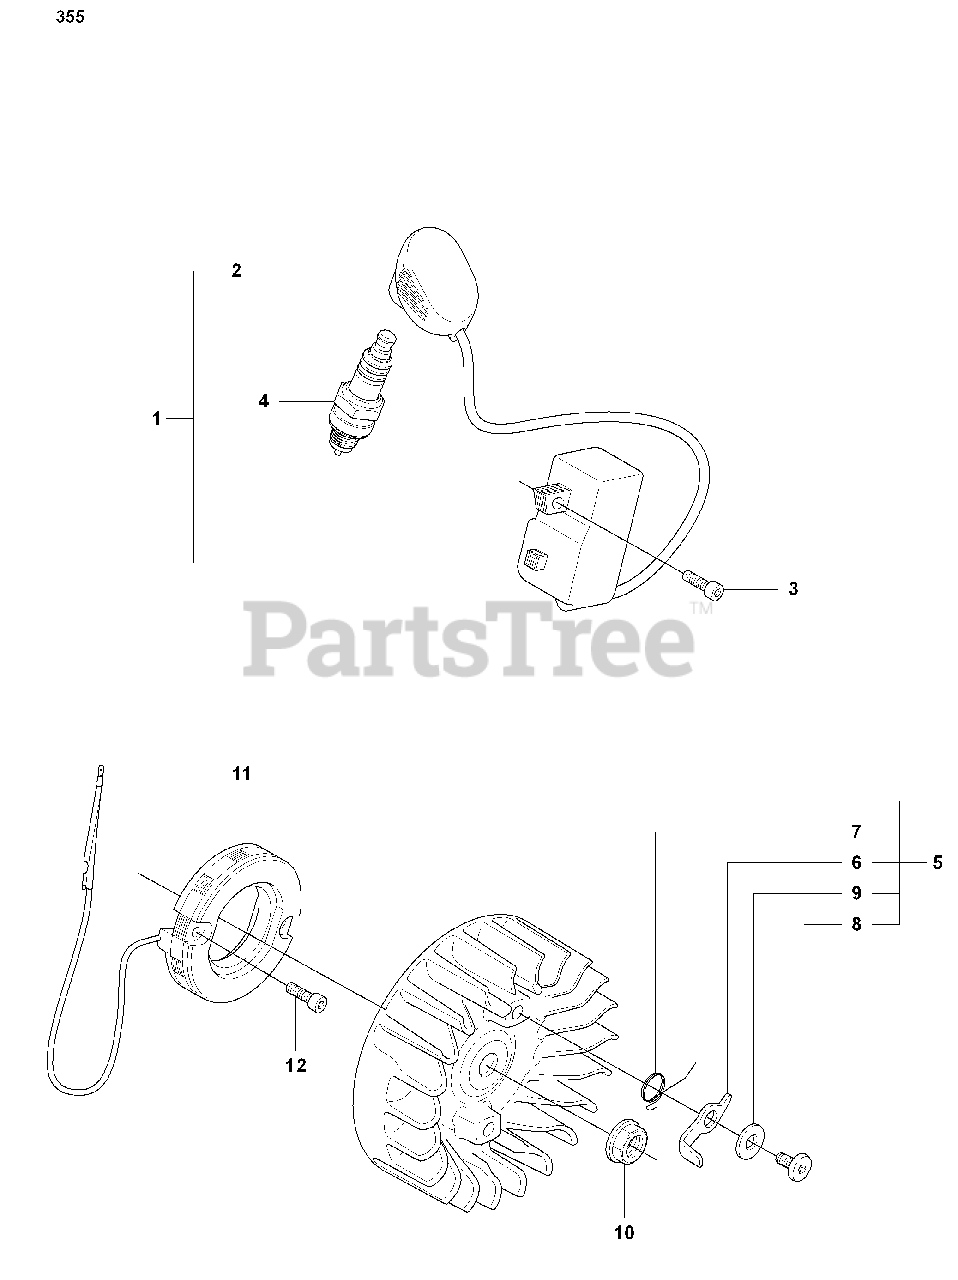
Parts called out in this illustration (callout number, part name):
1	RP IGNITION SYSTEM
1	IGNITION MODULE
2	SPARK PLUG CAP
4	BPMR7A NGK SPARK PLUG
5	FLYWHEEL ASSY
6	STARTER PAWL
7	SPRING
10	NUT W/ WASHER
11	GENERATOR STARTER
12	SCREW
